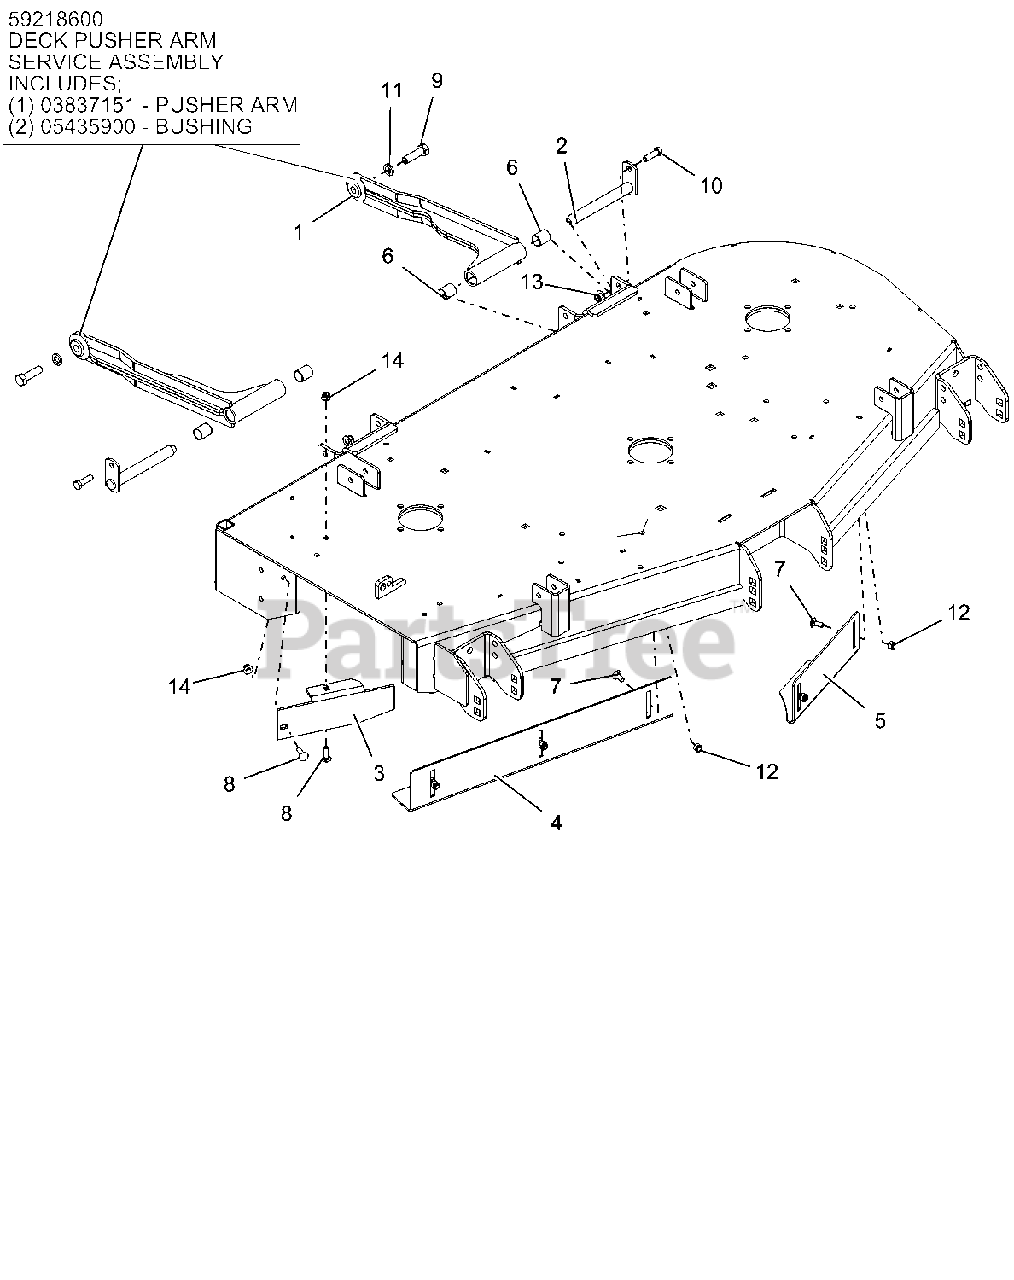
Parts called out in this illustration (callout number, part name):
1	WLDMT, DECK STABILIZER ARM
1	DECK PUSHER ARM SERVICE ASSEMBLY
1	PUSHER ARM
1	BEARING
2	WLDMT, MOWER MTG. PIN
3	BAFFLE, 52" DISCHARGE-RED
4	BAFFLE, 52" RH VACUUM-BLACK
5	BAFFLE, 52" LH VACUUM-BLACK
6	BRG, .750 X .875 X 1.000
7	BLT-RDHDSQNK .31-18X.75 G5 YWZC
8	BLT-RDHDSQSHNK .31-18X1.00 G5 Y
9	BLT-HEX .50-13X1.75 GR5 YWZC EP80
10	BLT-HEX .38-16X1.25 GR5 YWZC
11	WSHR-LK .50X.125 REG YWZC
12	NUT-LK-NYL .312-18 YWZC
13	NUT-LK-NYL-FLG .38-16 YWZC
14	NUT-LK-NYL-FLG .31-18 YWZC
